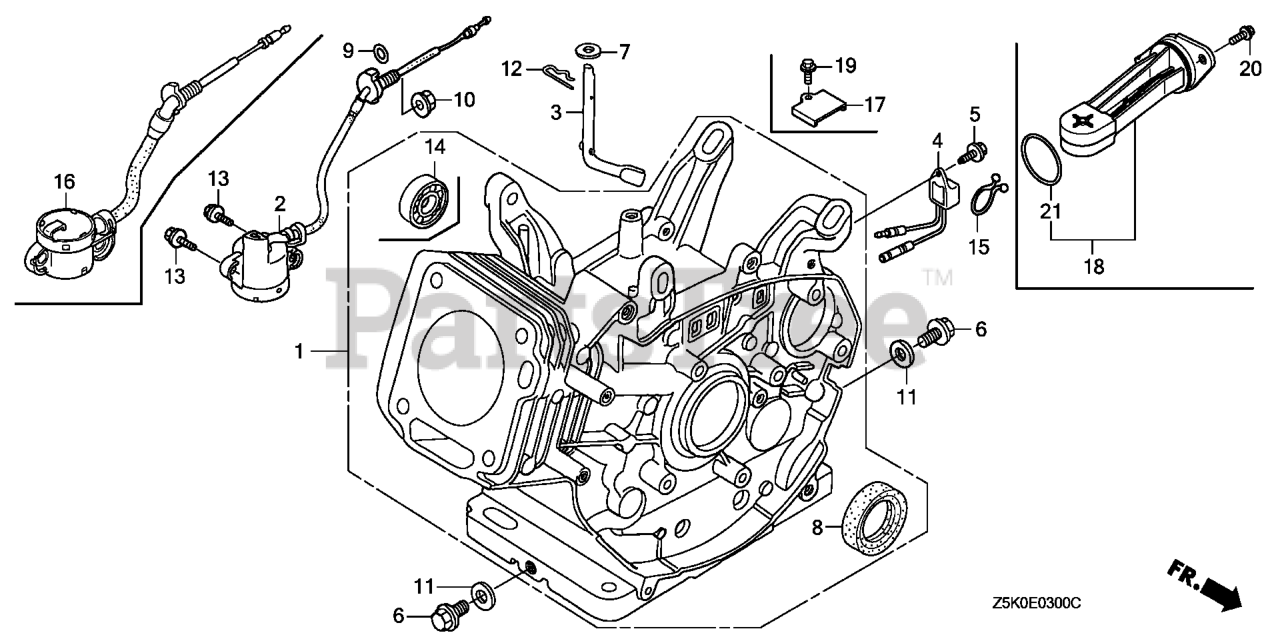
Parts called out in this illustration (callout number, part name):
1	CYLINDER ASSY.
3	SHAFT, GOVERNOR ARM
6	BOLT, DRAIN PLUG
7	WASHER (8.2X17X0.8)
8	OIL SEAL (30X46X8) (NOK ASIA)
8	OIL SEAL (30X46X8)
9	O-RING (14MM) (ARAI) Use up to Engine SN 2949254.
10	NUT, FLANGE (10MM)
11	WASHER, DRAIN PLUG (12MM)
12	PIN, LOCK (10MM)
13	BOLT, FLANGE (6X12) Use up to Engine SN 1543277.
14	BEARING, RADIAL BALL (6202)
16	SWITCH ASSY., OIL LEVEL
